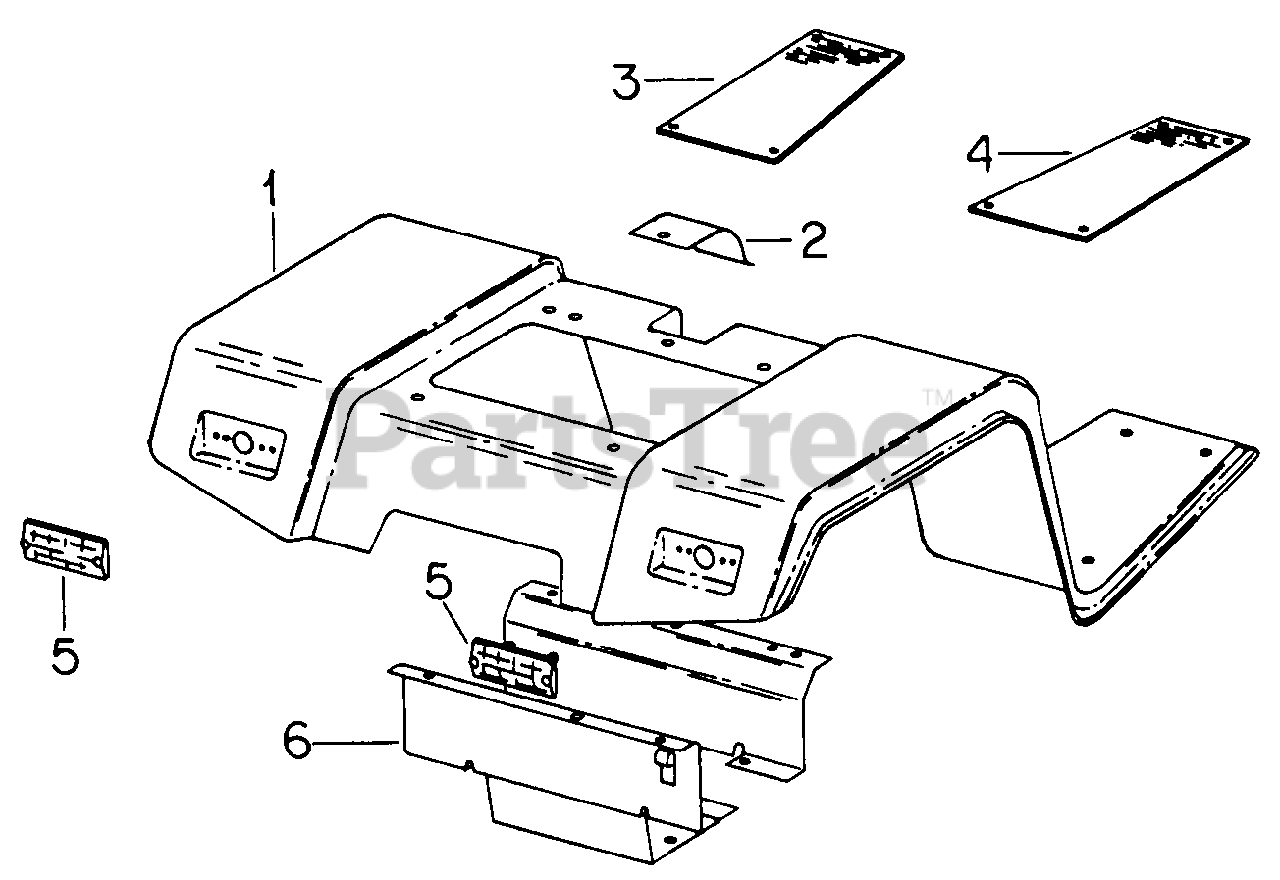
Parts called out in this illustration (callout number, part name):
2	Cover, Hydro Center
3	Tread, Platform, LH
4	Tread, Platform, RH
5	Not used this application
6	Support Assy, Fender
